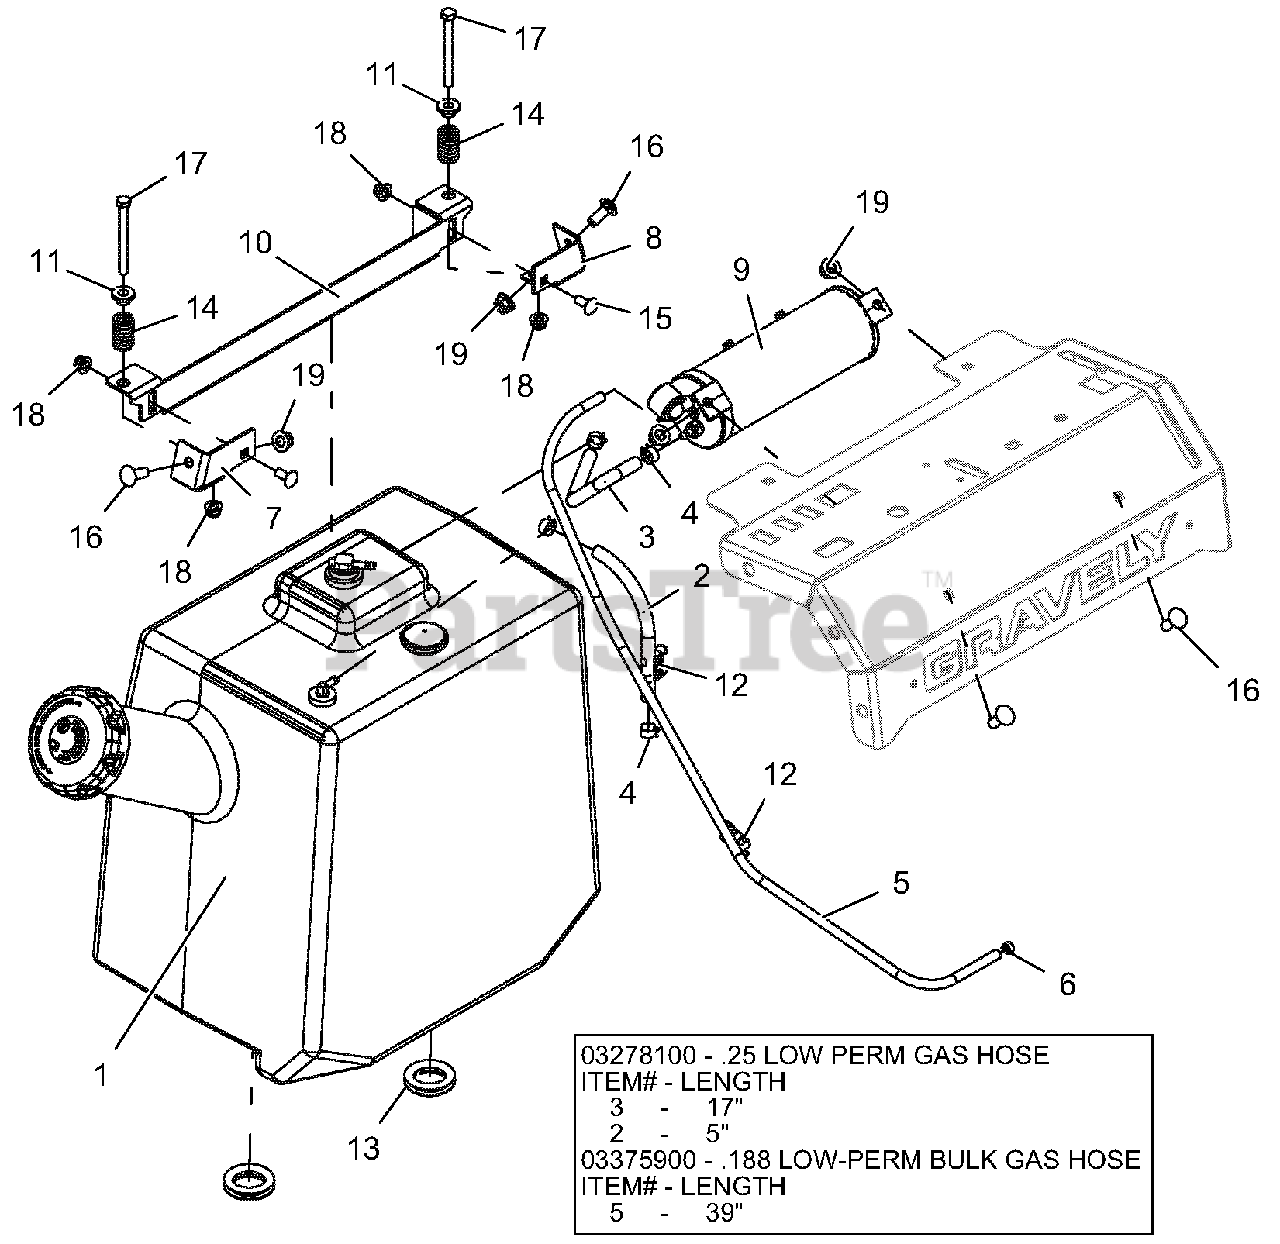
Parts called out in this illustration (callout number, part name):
1	ASSY, EPA PROSTANCE FUEL TANK
2	.25 LOW PERM GAS HOSE
3	.25 LOW PERM GAS HOSE
4	CLAMP, FUEL LINE
5	HOSE, .188 LOW-PERM BULK GAS
6	CLAMP - HOSE, SPRING .188
7	WLDMT, TANK HOLDDOWN - RH
8	WLDMT, TANK HOLDDOWN - LH
9	CANISTER, CARBON 9.3 GAL
10	HOLDDOWN, FUEL TANK
11	BSHG, FLG .385 x .500 x .875 x .406
12	CLIP, T, .38-.50
13	GROMMET, 1.25"
14	SPRG, COMPRESSION
15	BLT-RDHDSQNK .31-18 x .75 G5 YWZC
16	BLT-RDHDSQNK .38-16 x 1.00 G5 YWZC
17	BLT-HEX .31-18 x 3.25 GR5 YWZC
18	NUT-LK-NYL-FLG .31-18 YWZC
19	NUT-LK-NYL-FLG .38-16 YWZC
